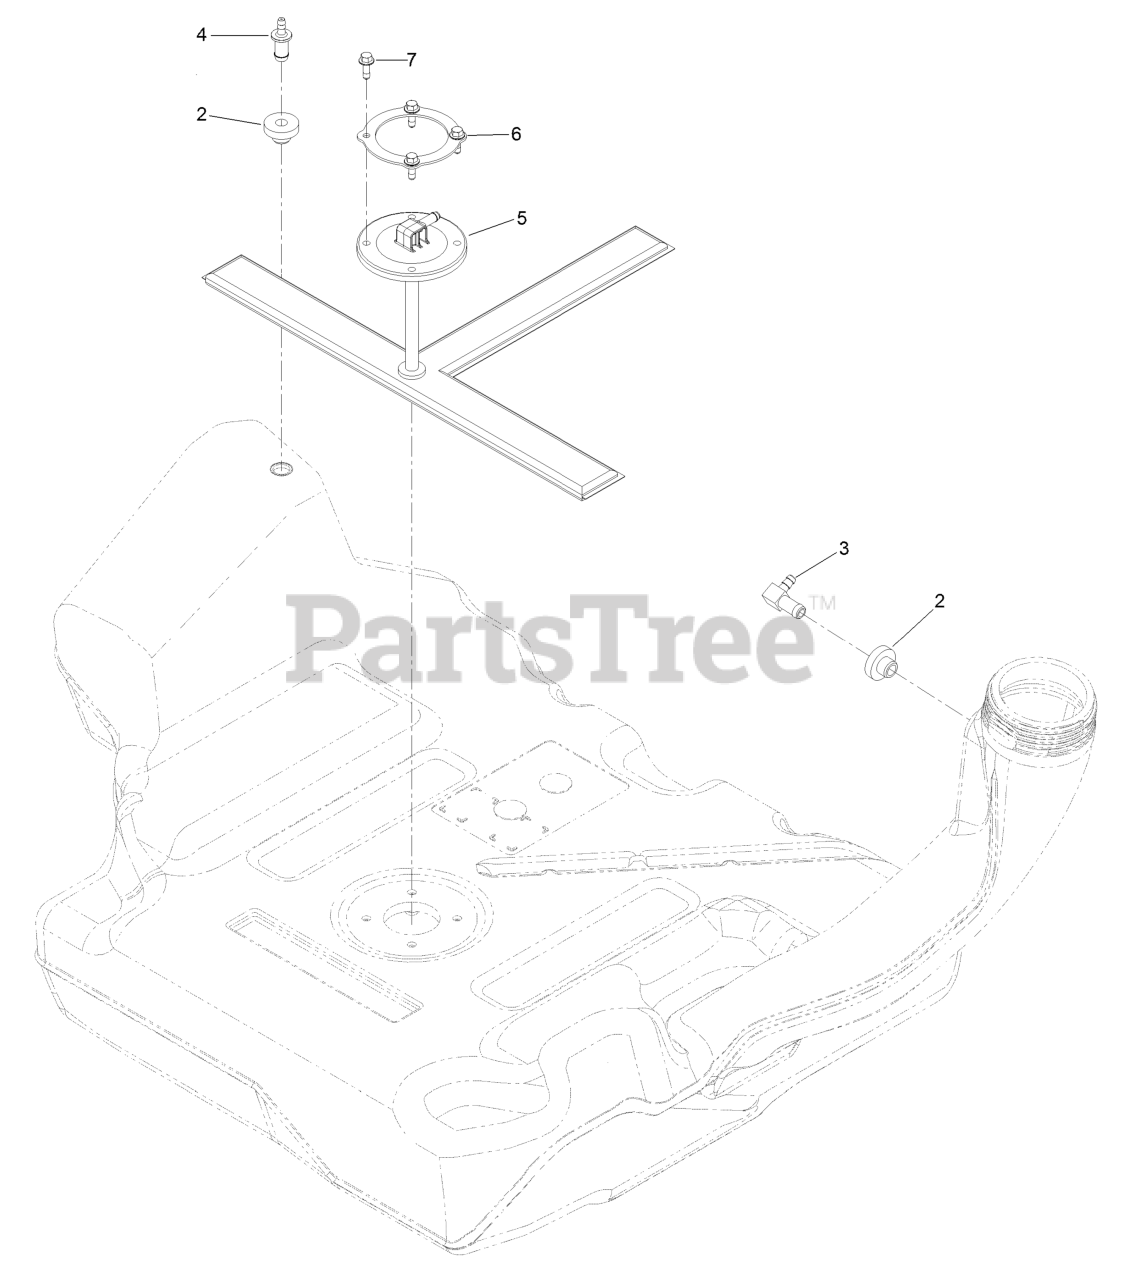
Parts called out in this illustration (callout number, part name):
2	Bushing
3	Fitting, 90 DEG
4	Fitting-Straight Orifice
5	Fuel Pickup
6	Ring-Retainer
